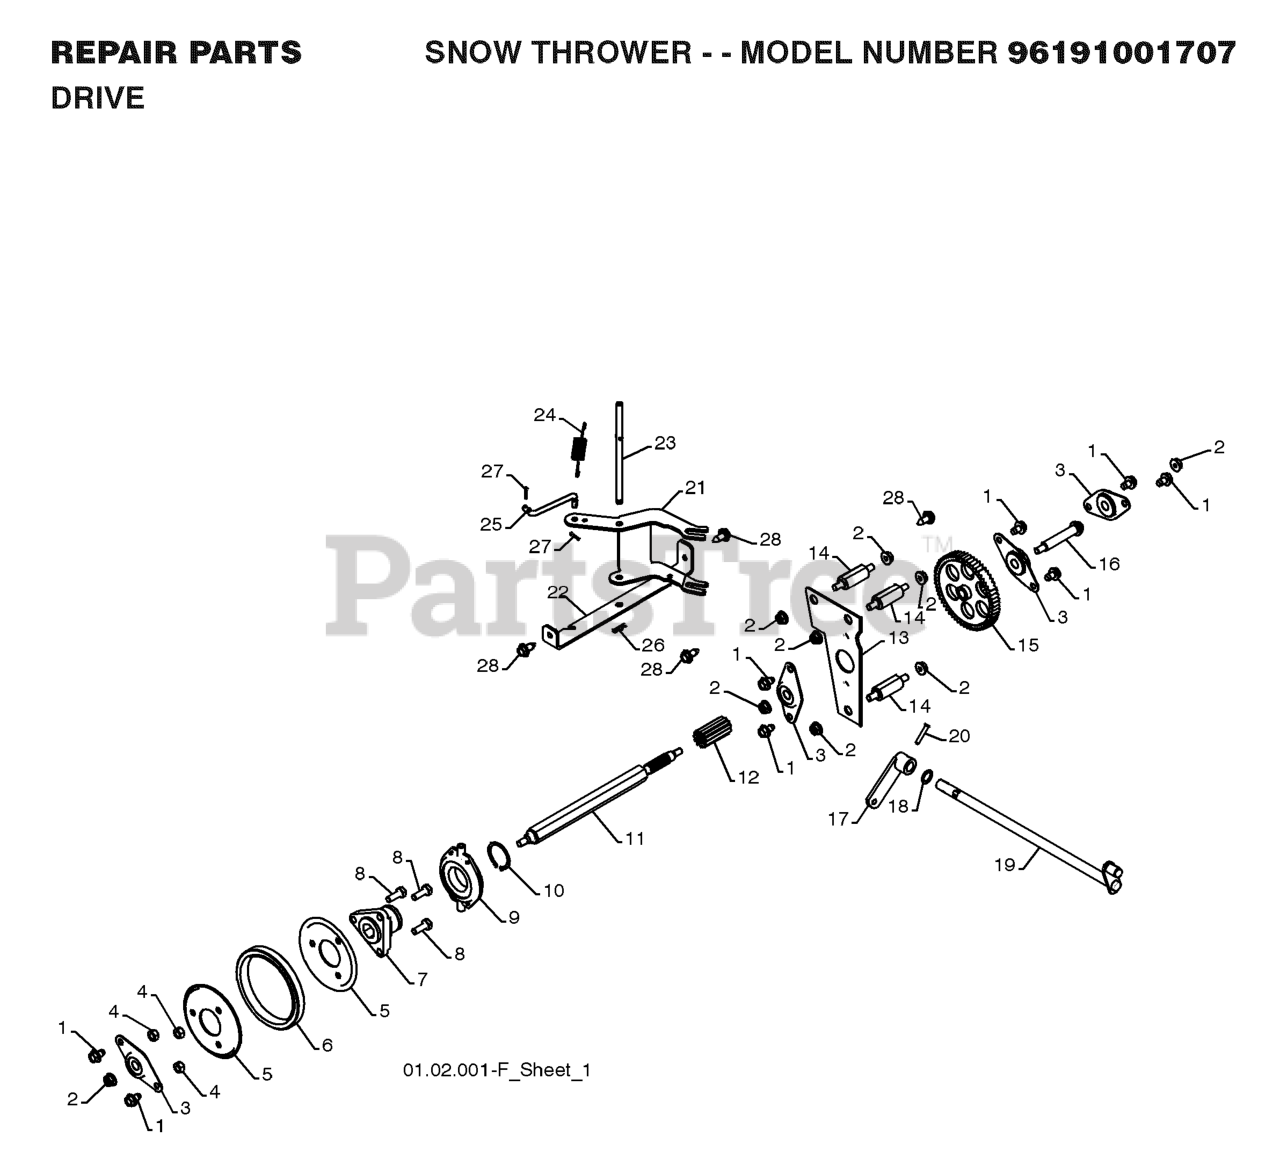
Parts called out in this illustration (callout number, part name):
1	Screw 5/16-18 x 1/2 Hex, Self Tapping 5/16-18 x 1/2
2	NUT.LOCK.5/16-18
3	BEARING, FLANGE
4	NUT.CENTERLOCK.5/16-
5	PLATE.RUBBER.WHEEL
6	RING, RUBBER WHEEL
7	HUB, RUBBER WHEEL
8	BOLT
9	TRUNNION BEARING ASSY
10	RETAINING RING (2 2)(3 2)
11	SHAFT.HEX.LONG
12	GEAR, PINION
13	AUXILLARY PLATE
14	SPACER, PLATE
15	GEAR, INTERMEDIATE
16	SHAFT, AUXILIARY
17	ARM, AUGER CONTROL
18	THRUST WASHER
19	SHAFT, AUGER CONTROL
20	CLEVIS PIN
21	LEVER, SPEED CONTROL
22	BRACKET, PIVOT, SHIFT
23	PIN, PIVOT
24	SPRING, BIAS
25	LINK, SPEED CONTROL
26	RETAINER CLIP PM
27	RETAINER CLIP
28	SELF-TAPPING SCREW 5/16-18X3/4
